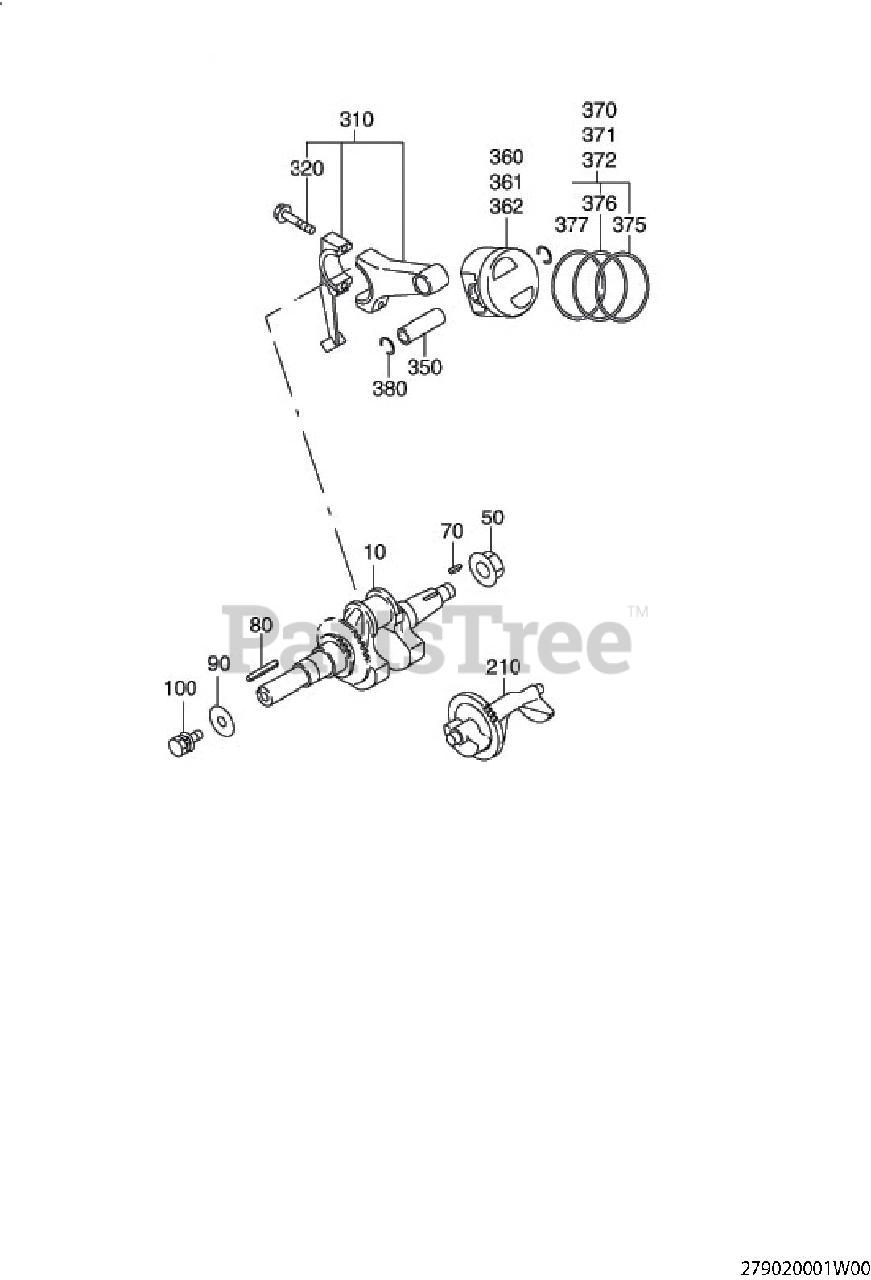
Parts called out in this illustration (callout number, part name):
10	CRANK SHAFT CP
50	FLANGE NUT
70	WOODRUFF KEY
210	BALANCER SHAFT
310	CONNECTING ROD AY
320	CONNECTING ROD BOLT
350	PISTON PIN
360	PISTON
361	PISTON
362	PISTON
370	PISTON RING SET
371	PISTON RING SET
372	PISTON RING SET
380	CLIP
